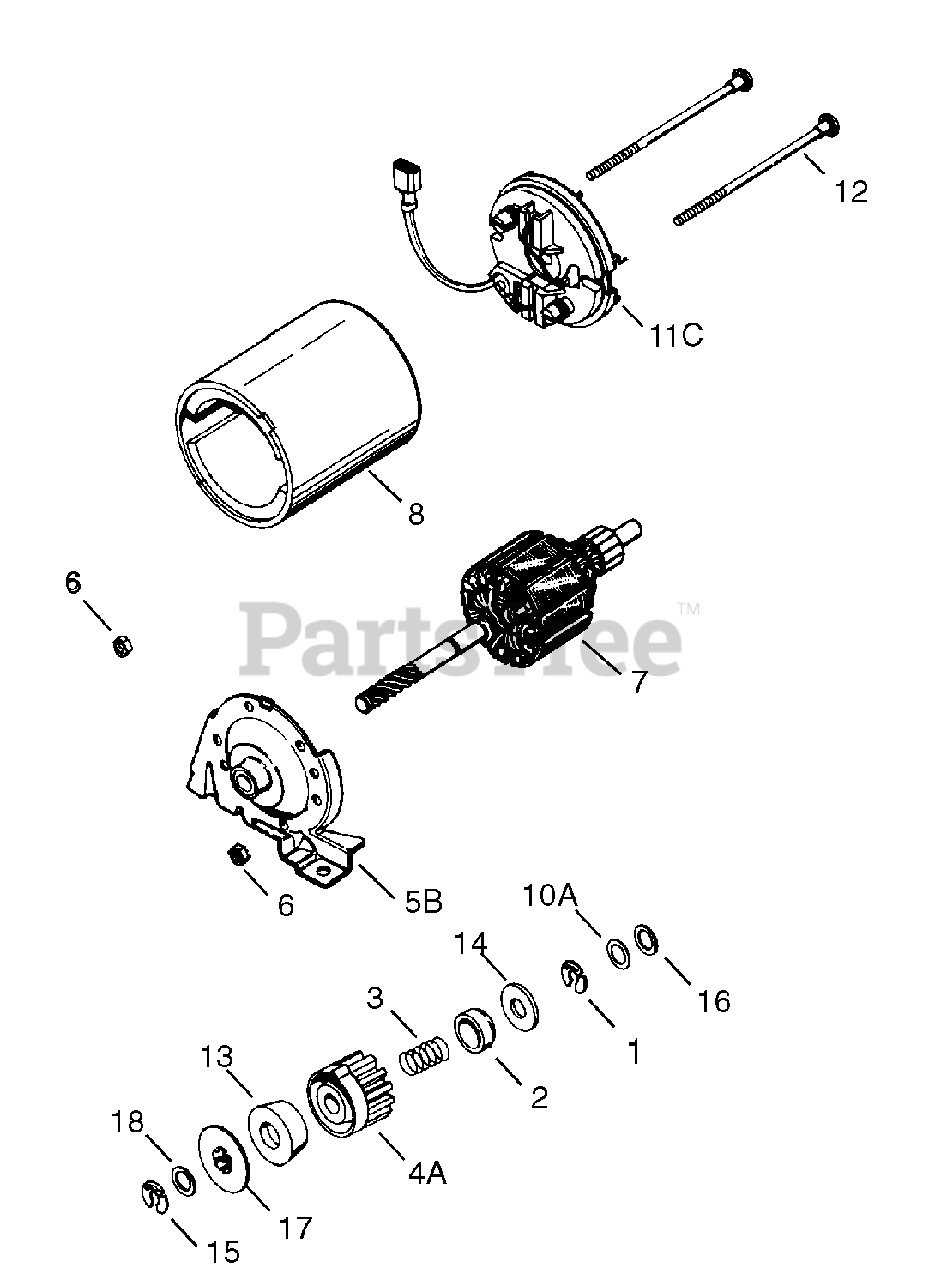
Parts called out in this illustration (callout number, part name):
1	Retainer Ring
2	Spring Retainer
3	Spring
4A	Gear
5B	Drive End Cap ASM
6	Lock Nut
7	Armature
8	Housing ASM
10A	Thrust Washer
11C	Commutator End Cap ASM (Incl. Brushes)
12	Bolt
13	Pinion Driver
14	Cup Washer
15	Retainer Ring
16	Washer
17	Drive Nut
18	Washer
